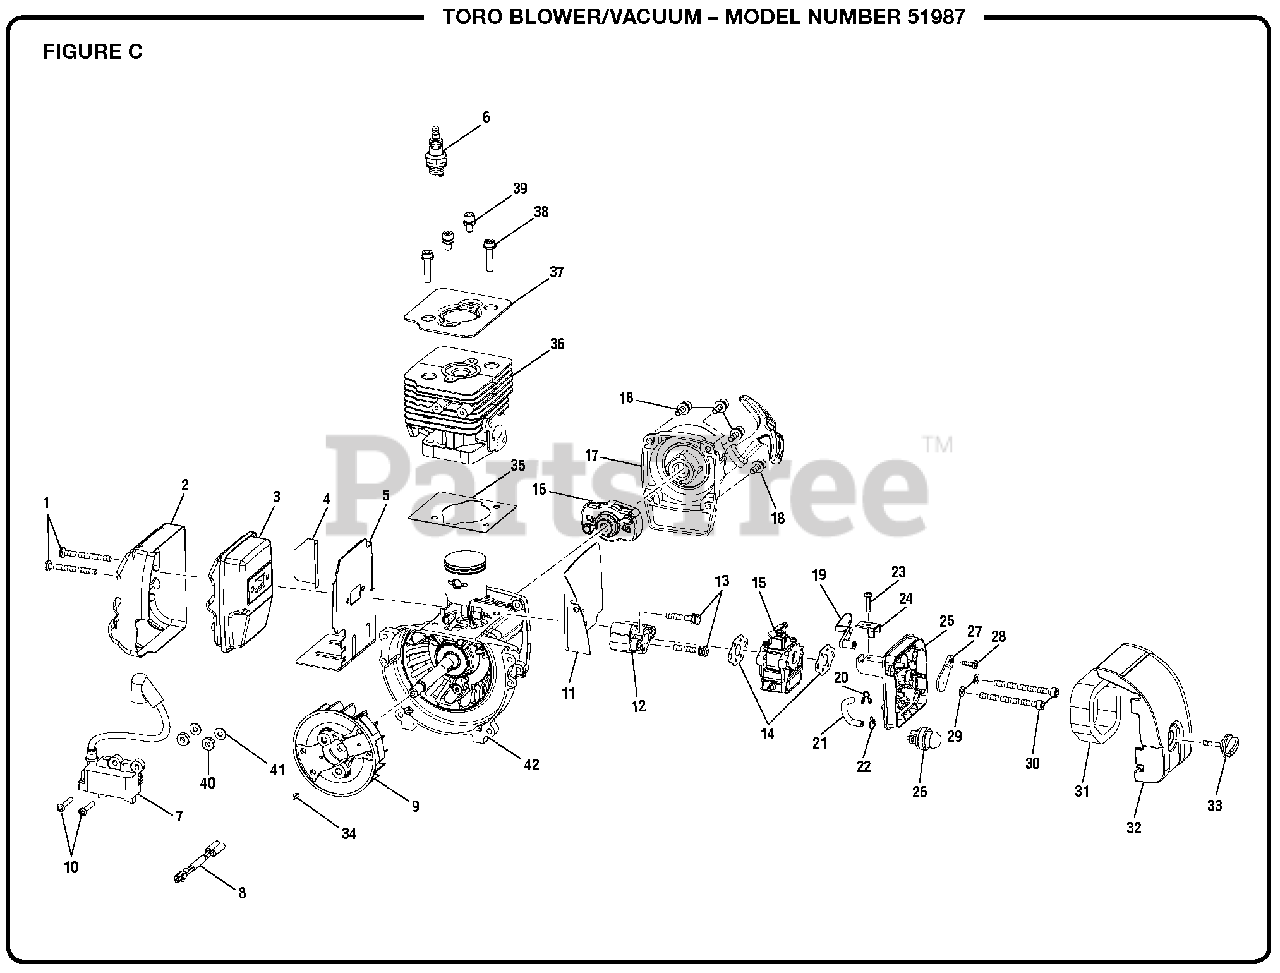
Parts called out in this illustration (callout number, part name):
1	Screw (M5 x 50 mm)
2	Muffler Heat Shield
3	Muffler Assembly
4	Heat Shield Tape
5	Muffler Gasket
6	Spark Plug (Champion RC6Y)
7	Ignition Coil Assembly
8	Ignition Lead Assembly
10	Screw (M4 x 22 mm)
11	Heat Dam Gasket
13	Screw w/Washer (M5 x 31 mm)
14	Carburetor Gasket
15	Carburetor Assembly
16	Pulley Assembly
17	Recoil Starter Assembly
18	Screw w/Washer (M5 x 16 mm)
19	Choke Lever
20	Hose Clip
21	Hose (51mm)
22	Hose Clip
23	Screw (M4 x 16 mm)
24	Retaining Clip
25	Air Box Case
26	Primer Bulb Assembly
27	Choke Plate
28	Screw (M4 x 12 mm)
30	Bolt (M5 x 60 mm)
31	Air Filter
32	Air Box Cover
33	Knob
34	Woodruff Key
37	Cylinder Plate
38	Bolt (M5 x 22 mm)
39	Bolt (M5 x 20.3 mm, Pan Hd.)
41	Washer (ID4.2 x OD10 x 1t)
42	Crankcase Assembly
